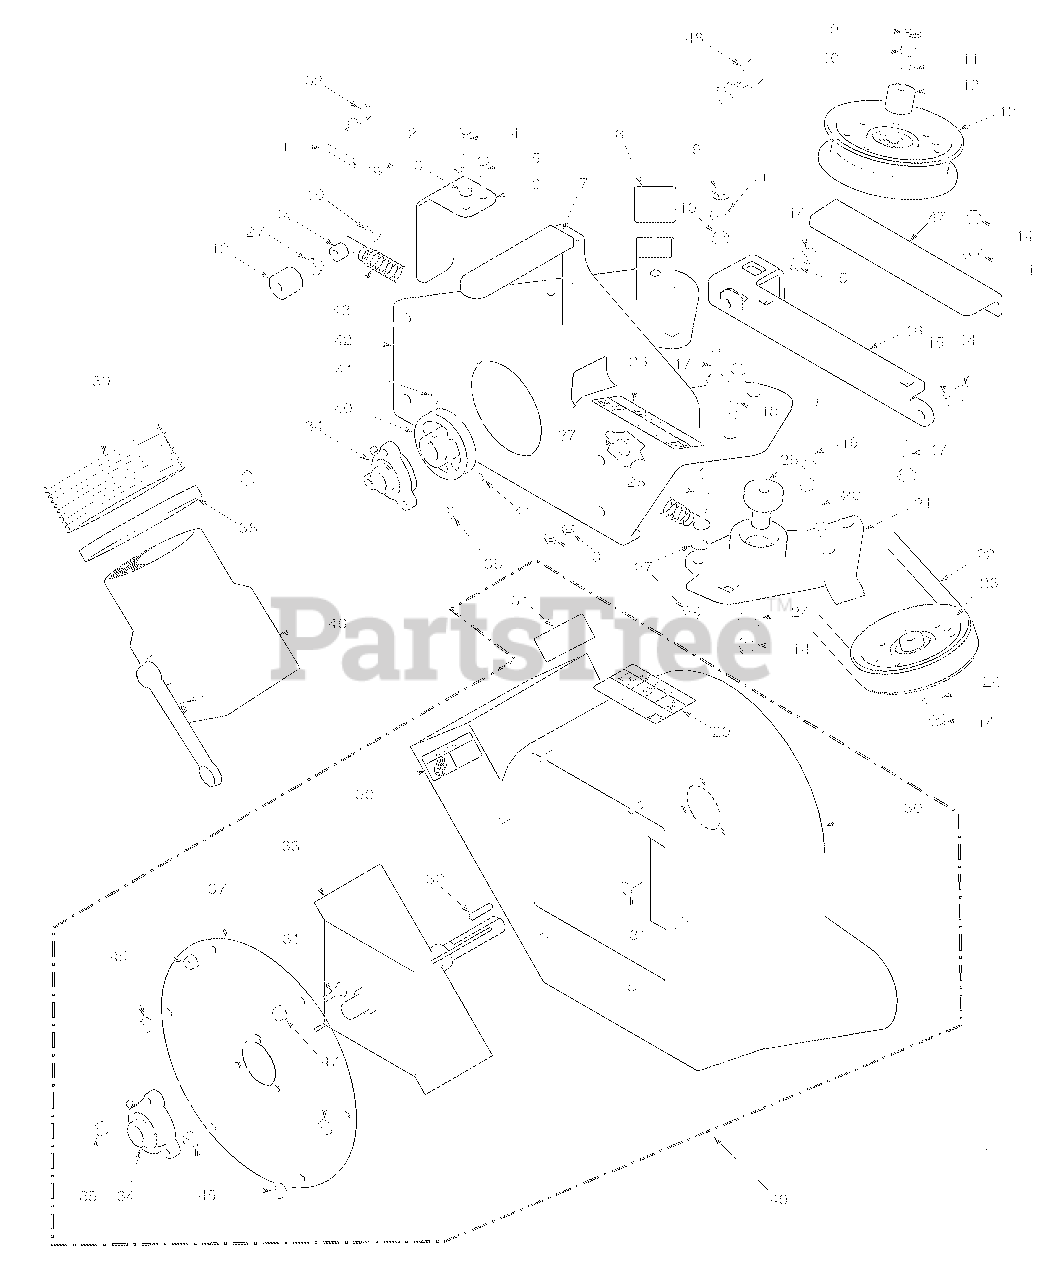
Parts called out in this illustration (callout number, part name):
1	Pin, Ring 2-1/4" Long
2	Lanyard, Deck Height Pin
3	Nut, Serr. Flange 1/4-20
4	Bolt, Hex Head 1/4-20 x 1-1/4"
5	Bolt, Hex Head 1/4-20 x 3/4"
6	Belt Cover, Rear
7	Grip, Blower Lever
8	Cap, Square
9	Nut, Push On 3/8 Thread
10	Lock Nut, 3/8-16
11	Flatwasher, 3/8-.391 x .938 x .105
12	Spacer
13	Pulley, Idler 4" Dia. - 61" & 72"
14	Nut, Elastic Stop 3/8-16
15	Lockwasher, 3/8-16
16	Plate, Catch Mounting
17	Bolt, Carr. 3/8-16 x 1-1/2"
18	Bolt, Hex Head 3/8-16 x 2-1/4"
19	Bolt, Hex Head 3/8-16 x 3-1/2"
20	Bolt, Hex Head 3/8-16 x 1-3/4"
21	Idler Arm Assembly, GC-STT 61"
22	Belt, GC-STT 61"
24	Washer, 3/8 Hardened
25	Pivot, Idler - 61" & 72"
26	Decal, Belt Cover
27	Nut, Serr. Flange 3/8-16
28	Bolt, Hex Head 3/8-16 x 1-1/2 Gr. 8
29	Decal, Danger
30	Blower Housing w/Decals
31	Bolt, Carr. 5/16-18 x 3/4" Gr. 5
32	Key, 1/4 x 1/4 x 1-1/2"
33	Fan Weldment
34	Bearing Assembly
35	Nut, Elastic Stop 5/16-18
36	Flatwasher, 5/16-.344 x .688 x .065
37	Cover, Blower Housing
38	Clamp, 8-5/8" Max Dia.
39	Hose, 8.00" Dia. x 60.50" Long
40	Pulley, 4-3/4" O.D. - 1" Bore
41	Set Screw, 5/16-18 x 3/8"
42	Frame, Blower Mount - 61"
43	Spring, Main Drive
44	Spacer
45	Nut, Serr. Flange 5/16-18
46	Adapter w/Strap
47	Plate, Blower Catch
48	Hair Pin Cotter, .243 x 4"
49	Blower Housing Assembly, GC-STT
50	Decal, Rotating Blower
51	Decal, Blower
52	Hair Pin Cotter, .177 x 3-1/4"
